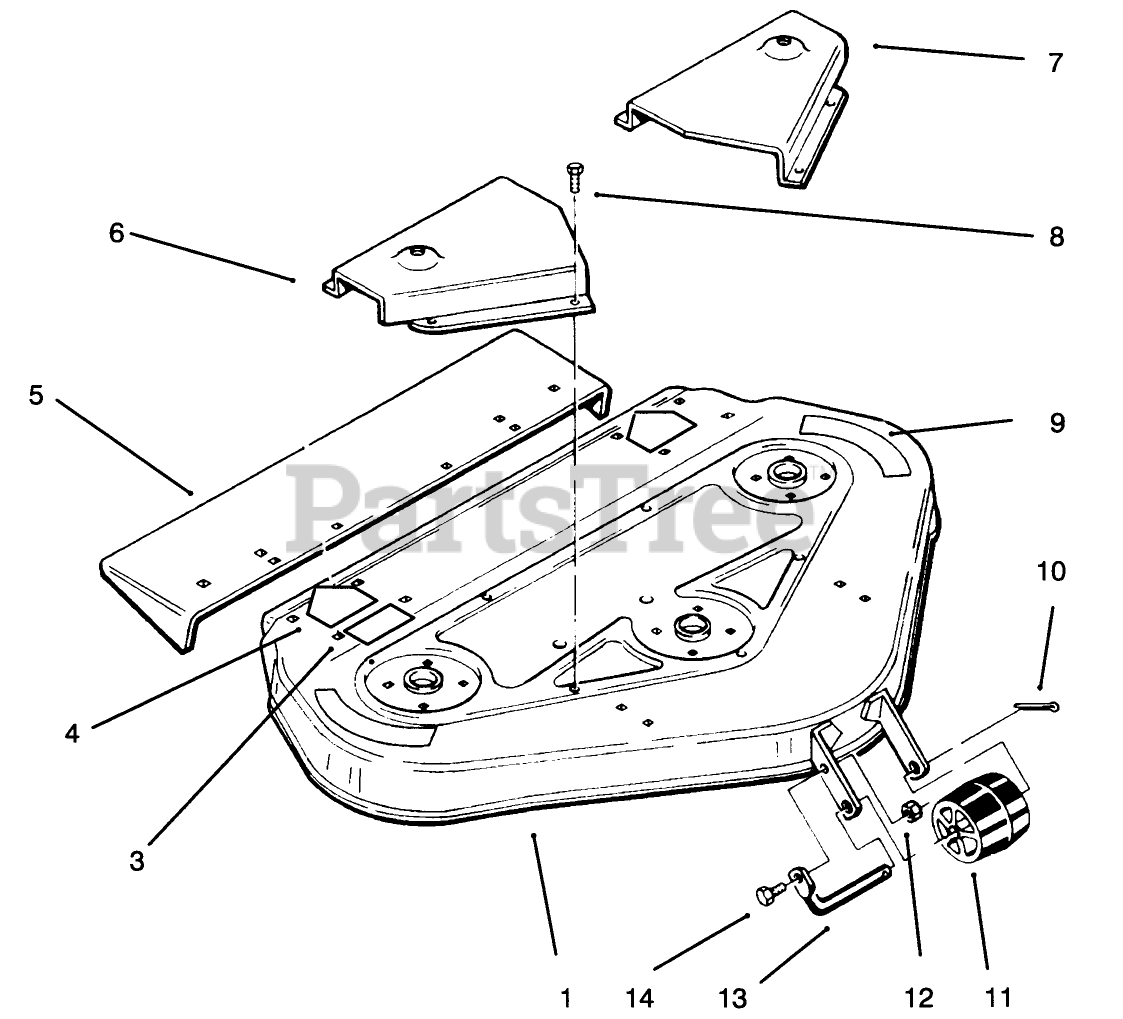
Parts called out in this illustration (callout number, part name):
1	Deck Ass-y (Incl. Ref. #4 & 9)
3	DECAL-HEIGHT & BELT
4	DECAL-DANGER
5	Chute Extension
6	Belt Cover RH
7	Cover-Belt
8	SCREW -4
9	DECAL - DANGER
10	PIN-COTTER
11	ROLLER ASSY
12	NUT-LOCK, NI
13	ROLLER-SHAFT
14	SCREW-HH
